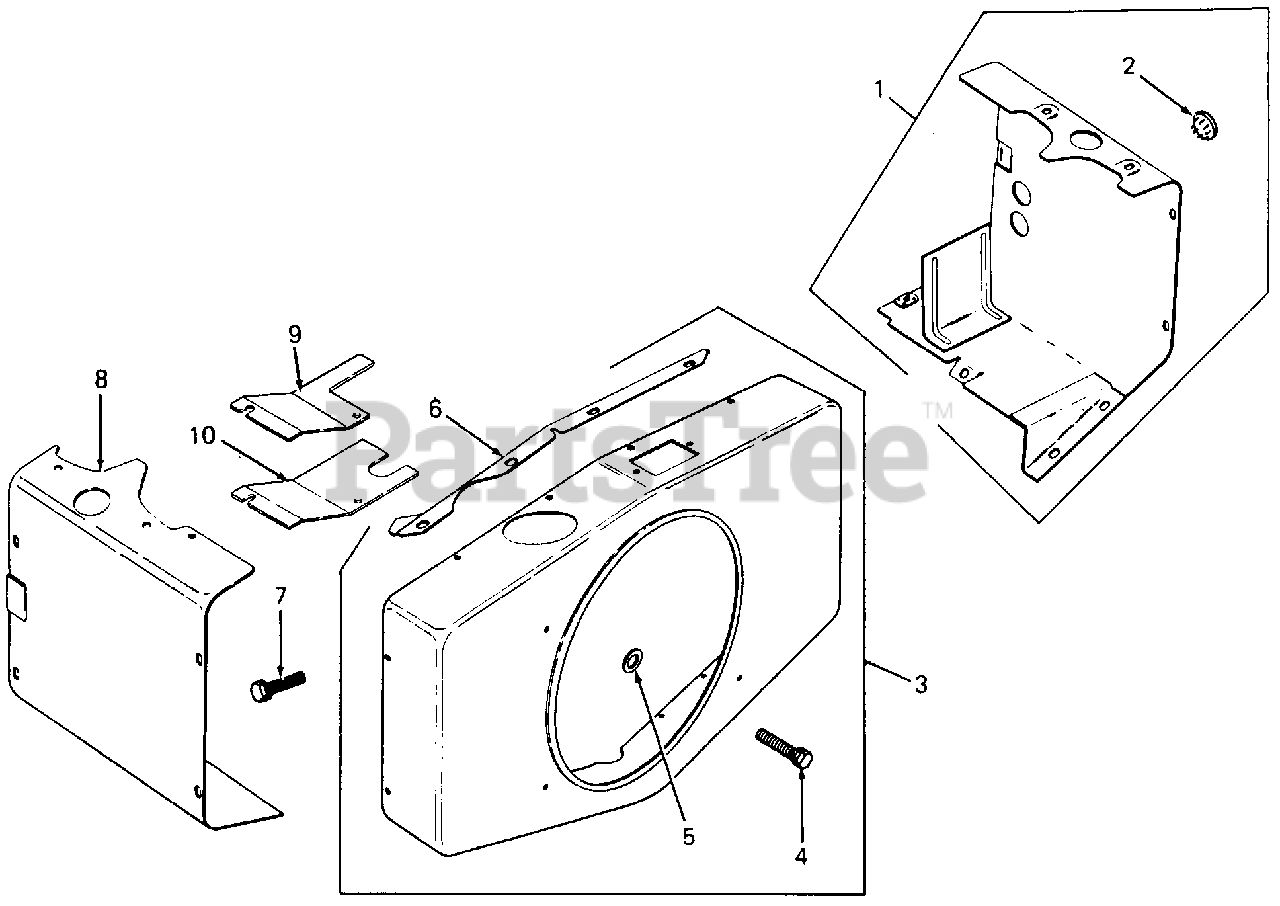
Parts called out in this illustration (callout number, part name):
1	Kit, #1 Cylinder Head Baffle
2	Plug, Button
3	Kit, Blower Housing
4	Screw, Self Tap, 1/4-20 X .62 Lg
5	Washer, Flat, 1/4
6	Support, Upper Housing
7	Screw, Hex Wash Hd, 1/4-20 X .43 Lg
8	Baffle, #2 Cylinder Head
9	Baffle, #2 Cylinder Top
10	Baffle, Pump
